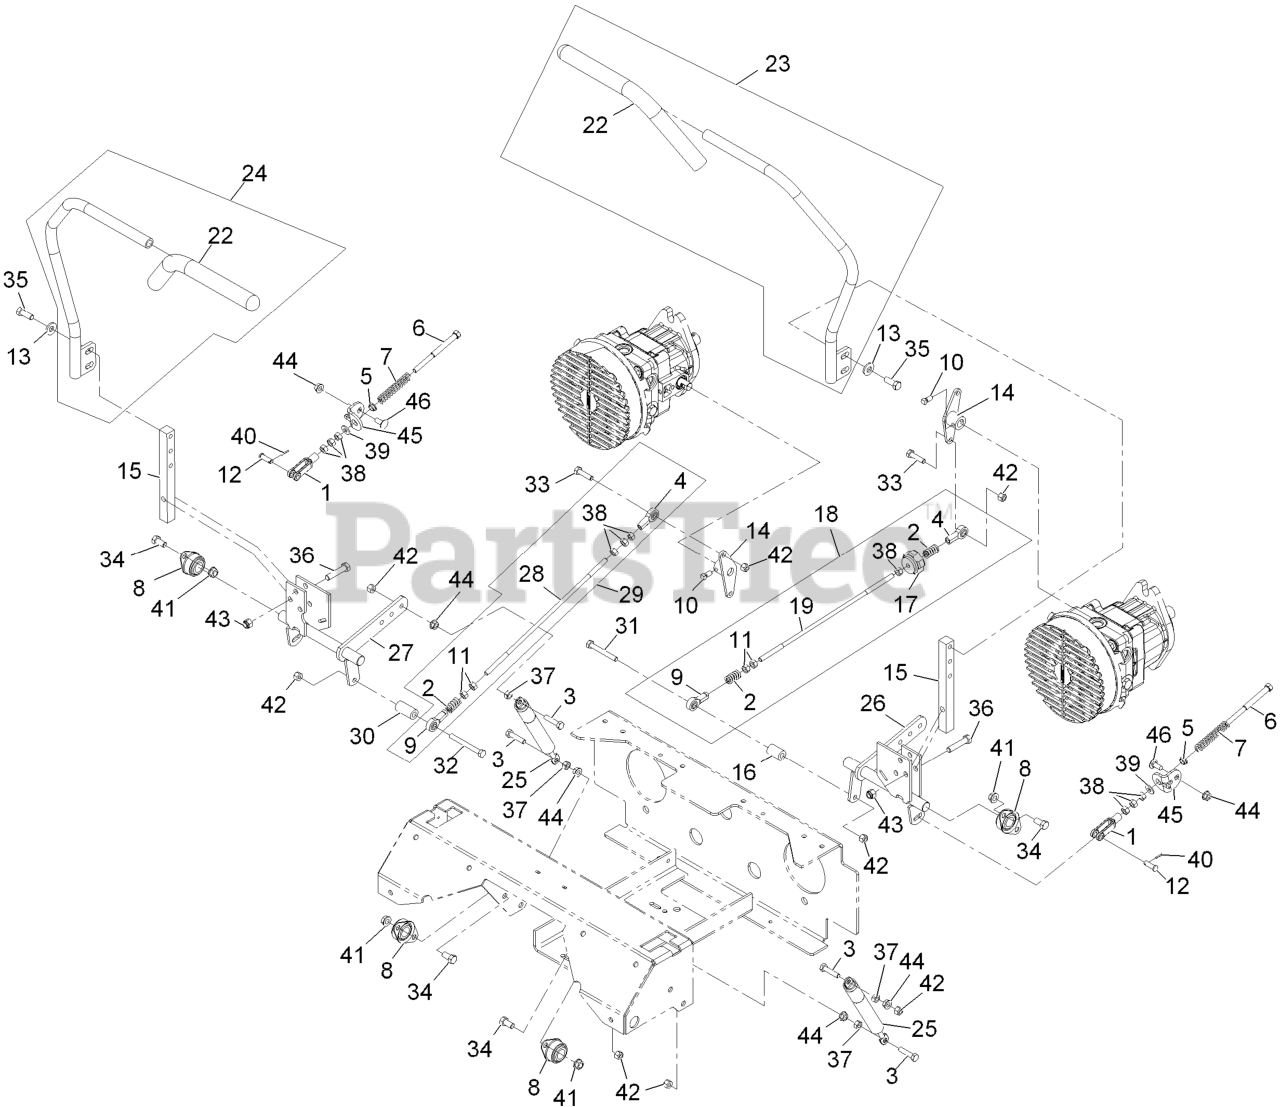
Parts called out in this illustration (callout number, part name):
1	YOKE-ADJUSTABLE
2	SPRING-COMPRESSION
3	SCREW-HH
4	BALLJOINT-RH
5	BUSHING-NYLON, FLANGED
6	BOLT-RETURN, NEUTRAL
7	SPRING-RETURN, NEUTRAL
8	BEARING-FLANGE, SIDE
9	BALLJOINT-LH
10	SCREW-SET
12	PIN-CLEVIS
13	WASHER-BELLEVILLE
14	ARM-CONTROL, HYDRO
15	ARM-SHAFT, CONTROL
16	SPACER-HYDRO CONTROL, LH
17	KNOB-TRACKING
18	TRACKING ROD ASM
19	LINK,TRACKING ROD XP
22	GRIP,CONTROL LEVER
23	ASM,LH LEVER/GRIP
24	ASM.RH LEVER/GRIP
25	DAMPER-CONTROL, MOTION
27	CONTROL-MOTION, RH
28	LINK,XP HYDRO CONNECT RH
29	RH HYD CONNECT LINK ASM
30	SPACER-CONTROL, HYD
31	SCREW-HH
32	SCREW-HH
33	SCREW-HH
34	SCREW-HH
35	SCREW-HH
36	SCREW-HH
37	NUT-HEX
38	NUT-HEX
39	WASHER-FLAT
40	PIN-COTTER
41	NUT-HHF, WHIZ
42	NUT-LOCK, NI
43	NUT-LOCK, NI
45	TAB-ADJUSTMENT
46	SCREW-CARR
